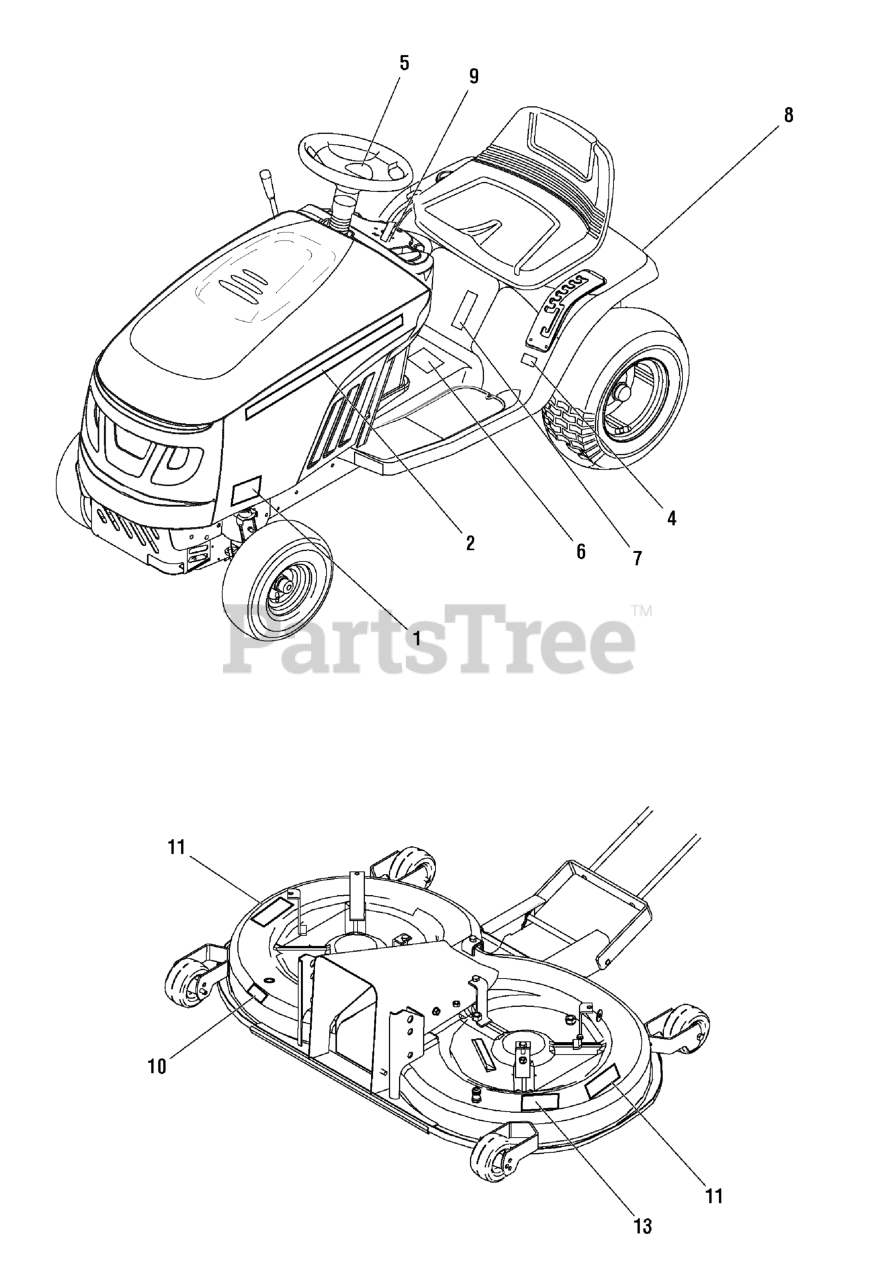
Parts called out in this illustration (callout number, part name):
1	DECAL, YK150RD
2	DECAL, Yard King Logo, Side
4	DECAL, 22HP
4	DECAL, 19.5HP
5	DECAL, Steering Wheel
6	DECAL, Tunnel Cover Warnings
7	DECAL, Fuel Level
8	DECAL, Hydro Release
9	DECAL, Ignition Switch
10	DECAL, Noise
11	DECAL, Safety
13	DECAL, Yard King
17	STICKER, Serial Number
